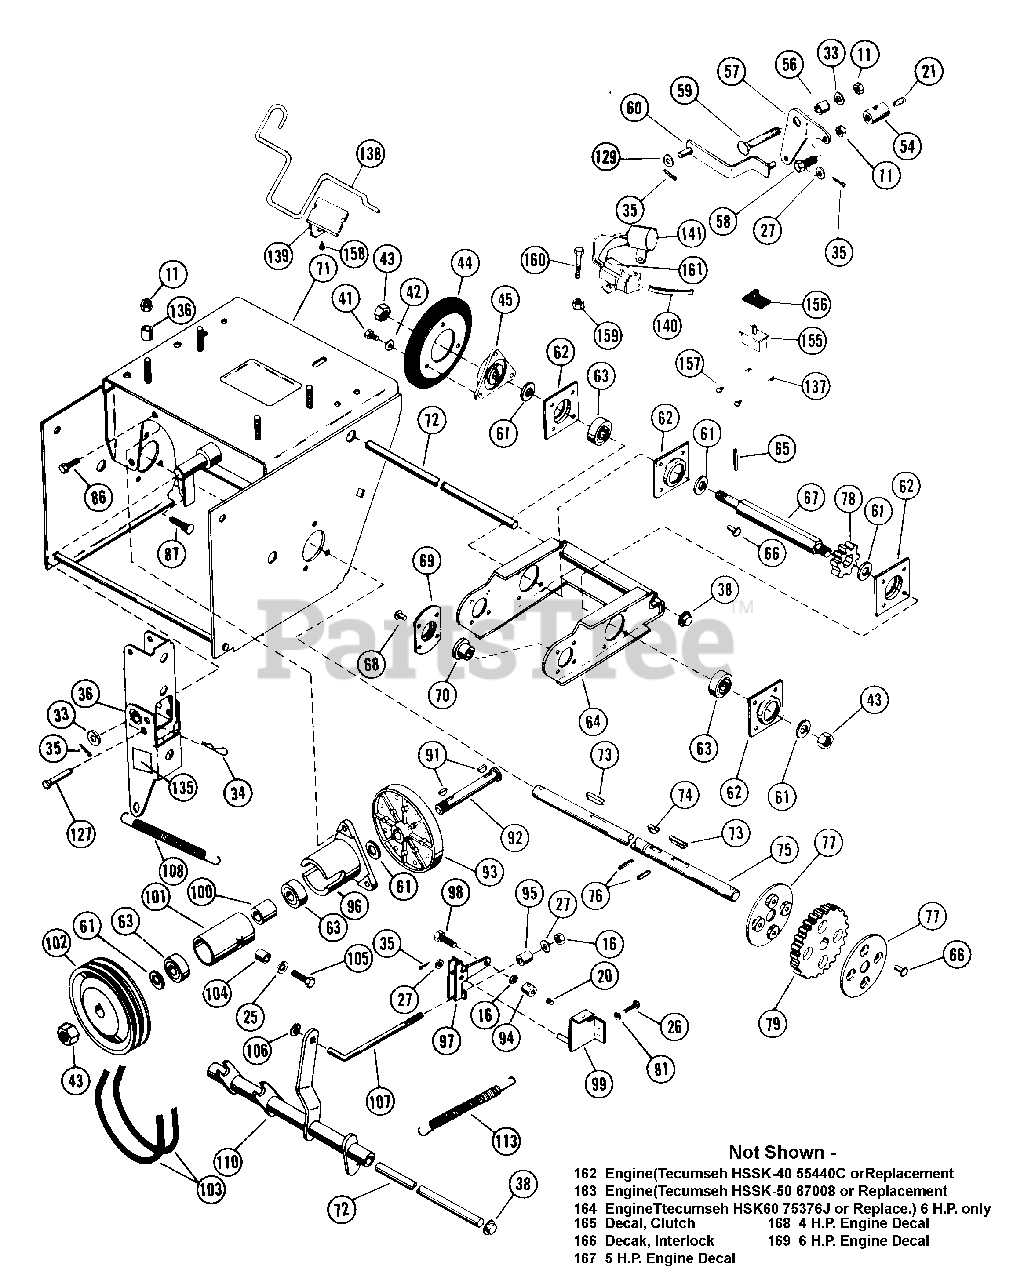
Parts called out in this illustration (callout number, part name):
1	BLT-HEX .31-18X1.50 PL GR2
2	WSHR-FL-STL.312X.734X.065PL
4	HANDLE PIVOT
5	SCR-TAP 12-14X1.50 CROVH PL BT
6	SPRINGGRIP FASTENER
7	SHIFT BALL
8	SHIFT HANDLE
9	SHIFT ROD
10	SG-COMP .105X.585X.75
11	NUT-LK .312-18 GR A PL
12	HANDLEBAR SERVICE ASSEMBLY
13	BLT-HEX .25-20X.75 PL GR2
14	THROTTLE CONTROL
15	BLT-RDHDSQNK .25-20X1.50 SHTPL
16	NUT-LK-CTR .250-20 PL
17	INNER BELT COVER
18	KEY-WDRF .125X.625X.250 SAE5
19	CAMSHAFT SHEAVE
20	SCR-SET .25-20X.25 SKHCUPNY OH
21	SCR-SET .32-18X.38 SKHCUPNL OH
22	KEY-SQ .188X1.0X.188 SAE 8630
23	BELT FINGER
24	BLT-HEX .31-24X.75 PL GR5
25	WSHR-LK .312X.097 PL HVY
26	BLT-HEX .25-20X.50 PL GR2
27	WSHR-FL-STL .250X.562X.049 PL
28	OUTER BELT COVER
29	BSHG-SLV .500X.625X.937
31	IDLER SHAFT
32	RVT-TBLR .187X1.218 OH ST PL
33	WSHR-FL-STL .38X.875X.083 PL
34	PIN-HAIR INT .08X.18X1.18
35	PIN-COTR .09X.75 PL
36	IDLER ARM ASSEMBLY
37	ENGINE SHEAVE
38	CAP, .50 ROD YWZC
39	BLT-SERHFWH .31-18X.50 PL
40	BLT-RDHDSQSHNK .31-18X.50 YZ
41	BLT-HEX .25-20X.38 PL GR2
42	WSHR-LK-EXT. 250 ID
43	NUT-LK-CTR .50-20 PL
44	FRICTION DISC
45	FRICTION DISC HUB
46	R H LOWER HANDLEBAR
47	NUT-LK-FLG .250-20 PL
48	R H UPPER HANDLEBAR
49	CLUTCH HANDLE
50	GRIP
51	CLUTCH ROD
52	BLT-HEX .25-20X1.75 PL GR2
53	L H LOWER HANDLE BAR
54	ROD ADAPTER
56	BSHG-SLV .334 X .502 X 1.437
57	SHIFT LEVER
58	BLT-HEX .31-18X.75 PL GR2
59	BLT-RDHDSQNK .31-18X2.0 SHT PL
60	SHIFT LINK
61	WSHR-FL-STL .505X1.000X.062
62	BEARING RETAINER
63	BRG-BALL .500X1.38X.437
64	CARRIER
65	PIN-ROLL .188X1.00
66	RVT-POP .187X.402 DOME ST
67	HEX SHAFT
68	RVT-POP.125 X .294 DOME
69	BEARING RETAINER
70	BSHG-FLG .750X1.000X.625X1.250
71	TRACTOR FRAME
73	KEY-FTHR .188X1.25X.187 SAE
74	KEY-WDRF .25X.750X.313 SAE91
75	AXLE SHAFT
76	PIN-ROLL .125X1.00
77	RETAINER PLATE
79	SPUR GEAR, FELLOWS 35T .750 ID
81	WSHR-LK .250X.077 HVY PL
82	L H UPPER HANDLEBAR
83	PIN-COTR .12 X 1.25 PL
85	WHL 10.25 IN O.D.
85	TIRE & WHEEL ASSEMBLY
85	TIRE 4.10/3.50-4
85	TUBE
85	T/WHL ASSY 4.80 X 8 AGRI LUG
85	WHL
85	BLT-HEX .38-16X.63 PL GR2
85	WSHR-LK .375X.094 MED PL
85	NUT-HEX .375-16
87	SCR-SLTR-SERNK .25-20X.62 PL
88	BLT-WHL .50-20X.75 GR5 PL
89	WHEEL HUB
90	SUPPORT, BEARING
91	KEY-WDRF .125X.500X.203 SAE 3
92	SPINDLE
93	DRIVE DISK
94	ROD ADAPTER
96	DRIVE SPINDLE HOUSING
97	DEADMAN LEVER
98	BLT-HEX .25-20X.75 PL GR5
99	DEADMAN BRACKET
100	BEARING SPACER .75 X .5 X.88
101	SPINDLE HOUSING
102	DRIVE SHEAVE
103	V-BELT, SPECIAL-RAW EDGE (SET)
105	BLT-HEX .31-18X1.00 PL GR 2
106	RATCHET PLATE
107	ADJUSTMENT LINK
108	SG-TENS .063X.44X2.81 WLD 18
109	ROD HANGER EYEBOLT
111	SPINDLE CUP
112	HUB CAP
113	SG-TENS .125X.437X5.5 WLD 20
115	CLUTCH LEVER ROD
116	WSHR-FL-STL .382X.812X.023 PL
117	SUPPORT BRACKET
118	UNIVERSAL JOINT ASSEMBLY
119	SCR-MCH .31-24X.75 CRFL
120	WSHR-LK-EXT .313X.025
122	PIN-COTR .12X1.0 PL
123	CLUTCH ROD
124	BLT-HEX .31-18X.75 PL GR2
125	PIN-ROLL .125X.75
127	CLEVIS PIN
129	WSHR-FL-STL .250X.562X.125 PL
130	HANDLEBAR DECAL
131	IN-OUT LABEL
132	DECAL WARNING
133	SHIFT DECAL
134	DISK ADJUSTMENT DECAL
135	IDLER ARM ADJUSTMENT DECAL
136	ENG BOLT SPCR
137	BRACKET SWITCH
138	ACTUATOR SWITCH
139	RETAINER ROD
140	WIRING HARNESS
141	MODULE T SERVICE ASSEMBLY
142	SNAP BUSHING-.437
143	SG-TENS 3.75 FREE LENGTH
144	SG-TENS .063X.44X1.56
145	UPPER ROD INTERLOCK
146	HANDLE INTERLOCK
147	PIN PIVOT
148	CONNECTING LINK
149	LOWER ROD INTERLOCK
150	PUSH NUT, .25
153	PIN-COTR .06X.50
154	NUT-HEX .250-20 PL
156	SWITCH BOOT
157	SCR-TAP 10-24X.375 CRPH 1A
158	SCR-TAP 10-24X.25 CRSLPH PL 1A
159	NUT-LK TOP 10-24 PL
160	BLT-HEX 10-24X.38 PL GR2
161	CONNECTOR
162	Engine(Tecumseh HSSK-40 5544OC orReplacement)
163	Engine(Tecumseh HSSK-50 67008 orReplacement)
164	Engine(Tecumseh HSK60 75376J or Replac.)6 H.P. only
167	5 HP ENGINE DECAL
168	4 HP ENGINE DECAL
169	6HP ENGINE DECAL
